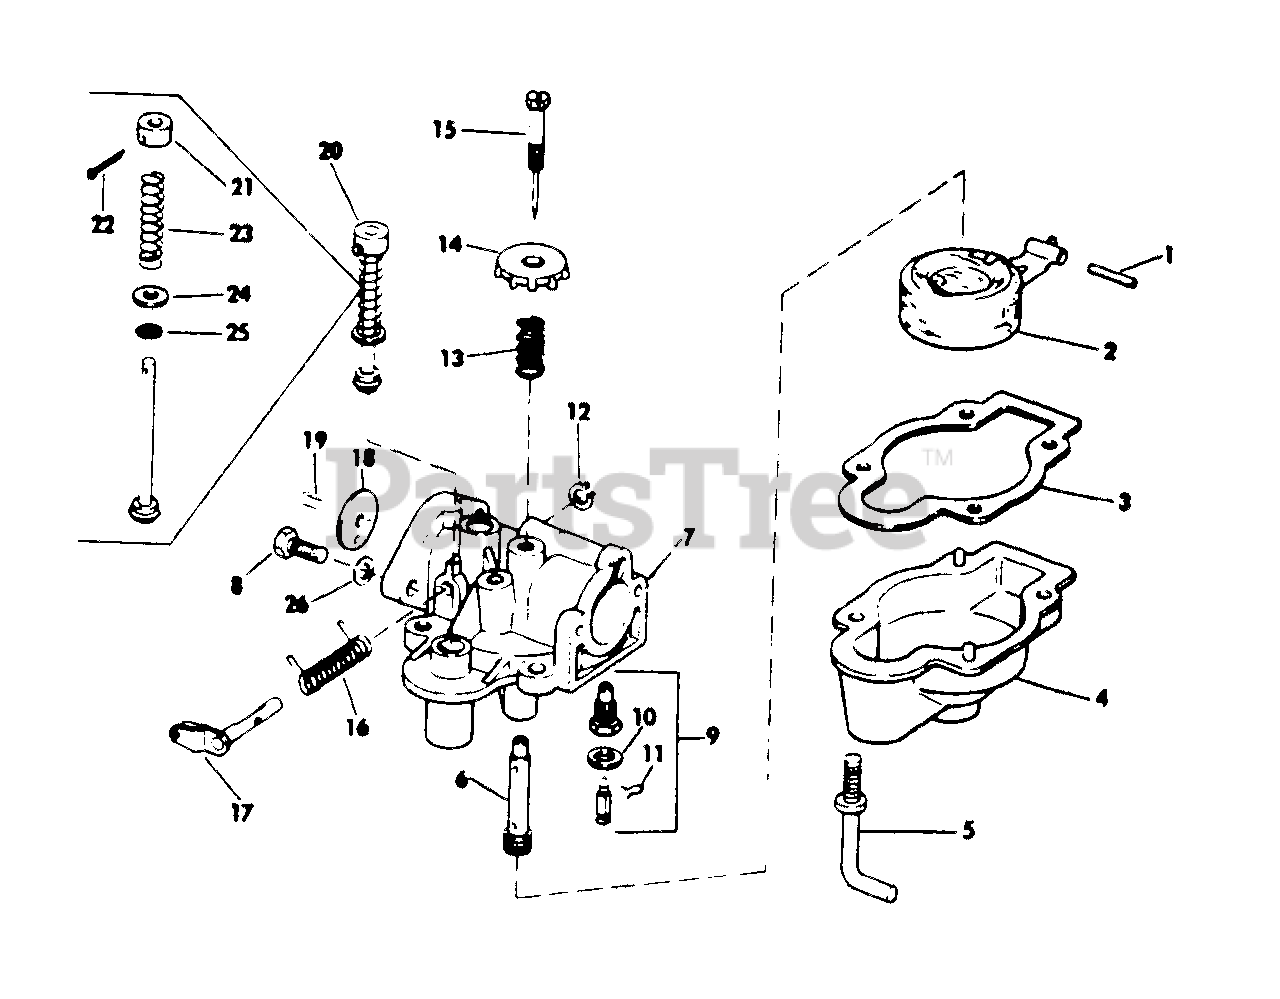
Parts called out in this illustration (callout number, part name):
1	Pin-Float Arm Hinge
2	Float & Arm Assembly
3	Gasket-Float Chamber
4	Chamber-Float
5	Screw-Float Chamber
6	Nozzle
7	Carburetor Body Assembly
9	Float Valve & Seat
10	Washer-Float Valve
11	Clip
12	Grip Ring
13	Spring-Needle Adjustment
14	Knob-Needle Adjustment
15	Needle Assembly
16	Spring-Throttle
17	Throttle Shaft & Lever Assembly
18	Disc-Throttle
19	Screw-Throttle Shaft Disc.
20	Primer Assembly
21	Knob-Primer
22	Cotter Pin
23	Spring-Compression
24	Washer-Plain
25	"O" Ring
76	Axle & Torque Lug Assy.
